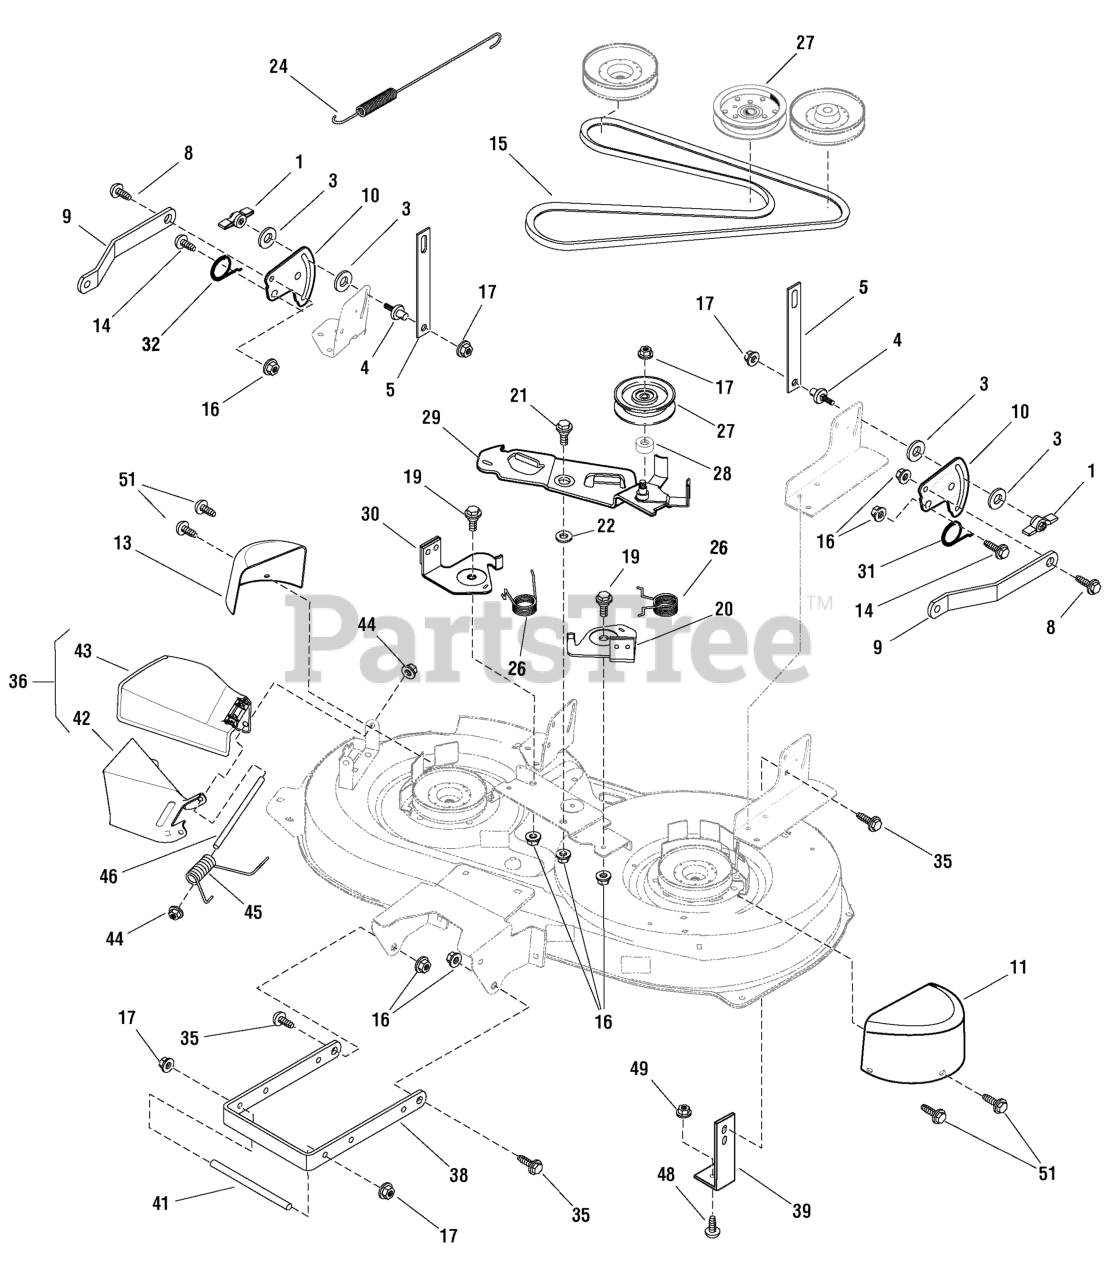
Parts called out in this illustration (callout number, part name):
1	KNOB (5/16-18 nut enclosed)
3	FRICTION PAD
4	PIN, Hanger
5	LINK, Lift (LT)
8	BOLT, Shoulder 3/8-16 x 1
9	BRACKET, Suspension
10	PLATE, Suspension
11	COVER, Belt, Left
13	COVER, Belt, Right
14	BOLT, Shoulder 3/8-16 x 1
15	BELT, V Mower Drive 38 in
16	NUT, Centerlock, 3/8-16
17	NUT Flange, 3/8-16
19	BOLT, Shoulder 3/8-16
20	BRAKE ASSEMBLY, Left
21	BOLT, Shoulder
22	WASHER, Flat
24	SPRING, Extension
26	SPRING, Torsion Brake
27	PULLEY, Idler, 4 in
28	SPACER, 1/2 in to 17 mm
29	ASSEMBLY, Idler Arm, 38 in
30	BRAKE ASSEMBLY, Right
31	SPRING, Left Torsion
32	SPRING, Right Torsion
35	CAPSCREW, 5/16-18
36	ASSEMBLY, Deflector
38	BRACKET, Suspension Front
39	BRACKET, Support
41	ROD HANGER
42	SUPPORT, Deflector
43	DEFLECTOR, Chute
44	CAP, Push On
45	SPRING, Torsion
46	ROD, Deflector
48	BOLT, Shoulder 5/16-18 x 1
49	NUT, Hex Flange, 5/16-18
51	SCREW, Hex 1/4 x 1/2
